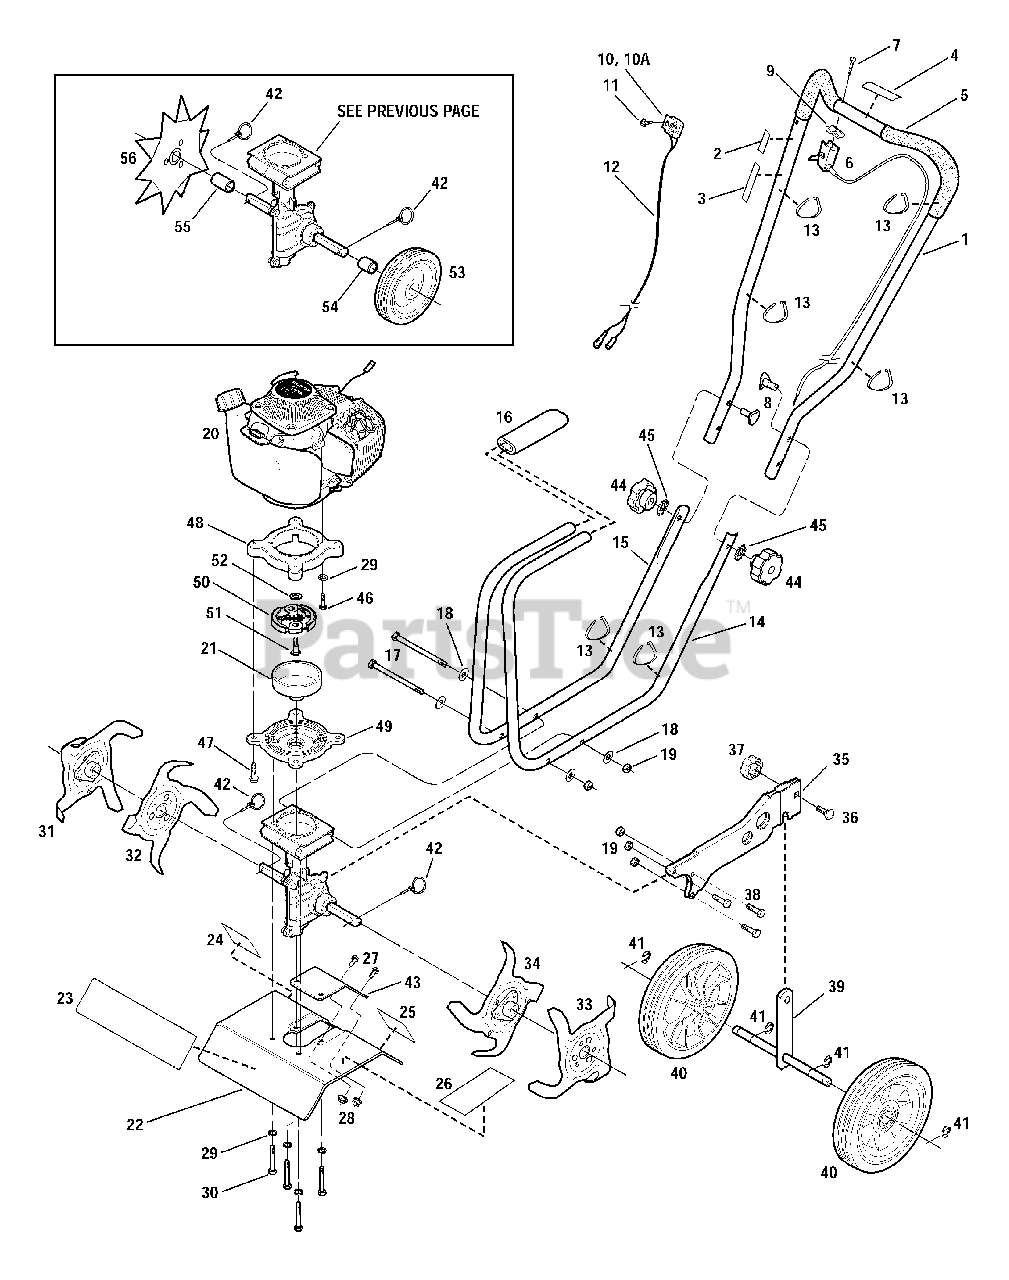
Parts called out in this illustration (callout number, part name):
1	Handlebar Assy.
2	Decal - On/Off Ignition Switch
3	Decal - Starting Stabilization
4	Decal - Throttle/Tines Control Lever Operation
5	Handlebar Grip, PVC
6	Throttle Lever and Cable
7	Pan Hd. Screw, #10-16 x 1-1/2
8	Saddle Hd. Screw, 5/16-18 x 2
9	Spacer, Throttle Lever
10	On/Off Ignition Switch
10A	Bracket - On/Off Ignition Switch
11	Phillips Hd. Screw, #12-24
12	Wire Assy. - On/Off Ignition Switch
13	Plastic Wire Tie
14	Lower Handlebar - Left-Side
15	Lower Handlebar - Right-Side
16	Foam Sleeve
17	Hex Hd. Screw, 1/4-20 x 5
18	Flat Washer, 1/4-20
19	Hex Locknut, 1/4-20
20	Engine
21	Clutch Drum and Hub
22	Tine Shield
23	Decal - Logo
24	Decal - Warning, Rotating TInes
25	Decal - Warning, Hot Surfaces
26	Decal - Caution, Operation Hazards
27	Hex Hd. Screw, #10-24 x 1/2
28	Flange Locknut, #10-24
29	Lock Washer, 1/4-20
30	Hex Cap Screw, 1/4-20 x 2
31	Outer Tine - Right-Hand Side
32	Inner Tine - Right-Hand Side
33	Outer Tine - Left-Hand Side
34	Inner Tine - Left-Hand Side
35	Wheel Bracket
36	Carriage Bolt
38	Hex Hd. Screw, 1/4-20 x 1
40	Wheel
41	E-Ring
42	Ring Lock Pin
43	Tine Hood Cover
45	Lock Washer, 5/16
46	Hex. Hd. Screw, M6 x 20
47	Hex Flange Screw, 5/16-18 x 1-1/4
48	Adapter Plate - Engine
49	Adapter Plate - Transmission
50	Clutch Assy.
53	Edger Wheel
54	Bushing - Short
55	Bushing - Long
56	Edger Tine
